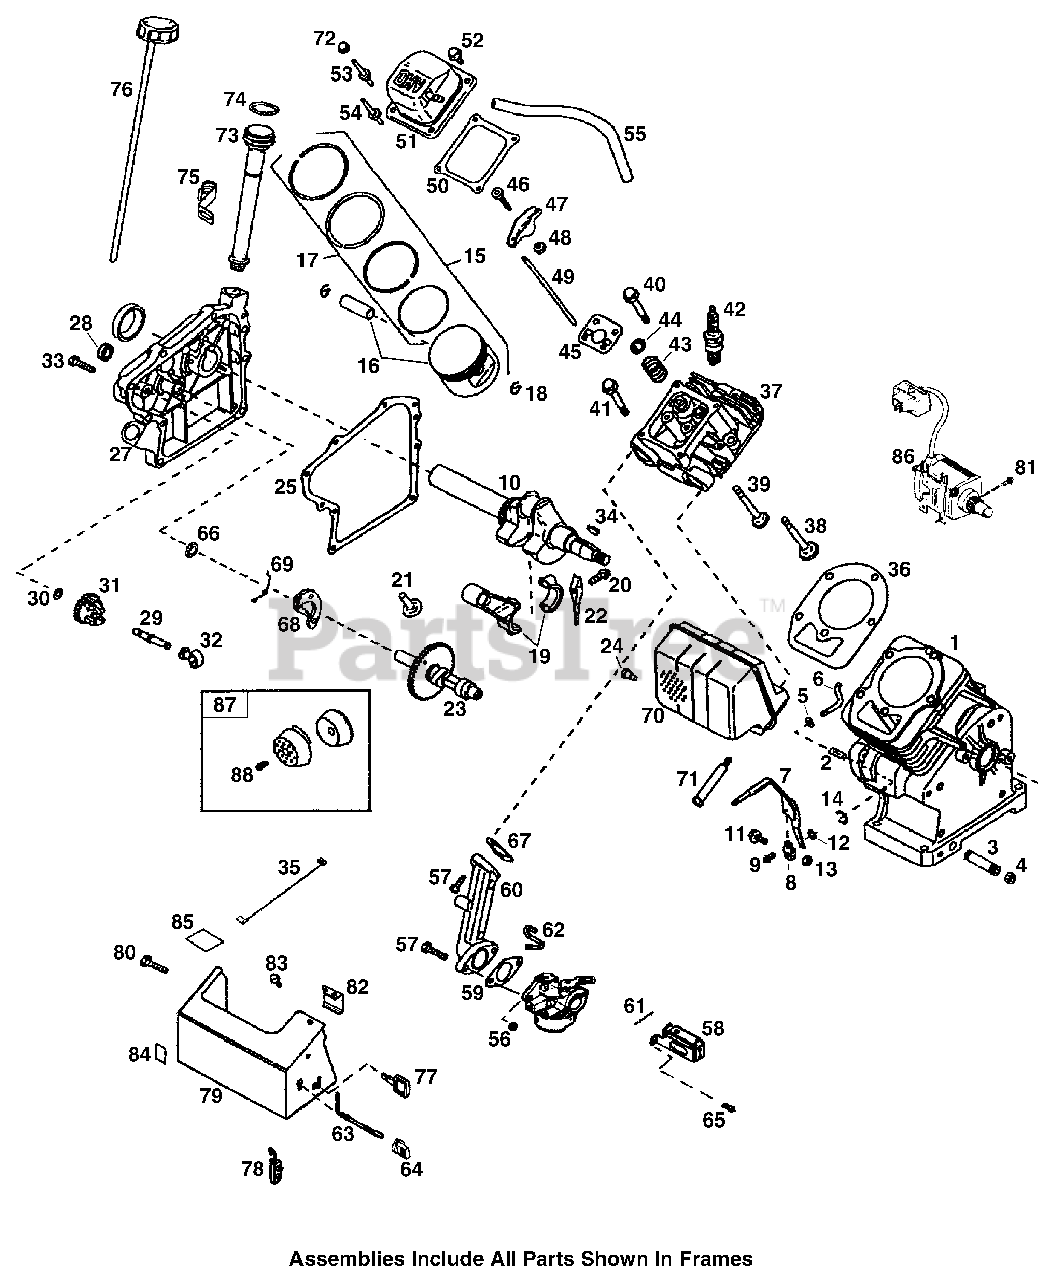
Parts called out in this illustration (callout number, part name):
1	Cylinder
2	Dowel Pin
3	Oil Drain Extension
4	Extension Cap
6	Governor Rod
7	Governor Lever
8	Governor Lever Clamp
9	Screw, Torx T-15, 8-32 x 3/8".
10	Crankshaft
11	Screw, 10-32 x 3/4".
12	Lock Washer
13	Lock Nut, 10-32
14	Retaining Ring
15	Piston, Pin & Ring Set (Standard)
16	Piston & Pin Ass’y (Standard)
17	Ring Set (Standard)
18	Piston Pin Retaining Ring
19	Connecting Rod Ass’y
20	Connecting Rod Bolt
21	Valve Lifter
22	Oil Dipper
24	Screw, 1/4-20 x 27/32".
25	Cylinder Cover Gasket
28	Camshaft Seal
29	Governor Shaft
31	Governor Gear Ass’y
32	Governor Spool
33	Screw, 1/4-20 x 1-1/4".
34	Flywheel Key
35	Ground Wire
36	Cylinder Head Gasket
37	Cylinder Head
38	Exhaust Valve (Standard)
39	Intake Valve (Standard)
40	Screw, 5/16-18 x 1-1/2".
41	Screw, 5/16-18 x 2-41/64".
42	Resistor Spark Plug (N4C)
43	Valve Spring
44	Valve Spring Cap
45	Push Rod Guide
46	Rocker Arm Stud
47	Rocker Arm
48	Nut, 1/4-28
50	Rocker Arm Cover Gasket
51	Rocker Arm Cover
52	Screw, 1/4-20 x 31/64".
55	Breather Tube
56	Nut, 1/4-20
57	Screw, 1/4-20 x 1".
58	Choke Bracket
59	Carb. to Intake Pipe Gasket
60	Intake Pipe
61	Choke Spring
62	Throttle Link
63	Choke Rod
64	Choke Knob
65	Screw, 10-32 x 1/2".
67	Intake Pipe Gasket
68	Compression Release Weight
69	Compression Release Spring
70	Muffler
71	Screw, 1/4-20 x 2-9/32".
72	Nut & Lock Washer
73	Oil Fill Tube
75	Fill Tube Clip
77	Ignition Key
79	Carburetor Cover
80	Screw, 10-32 x 1/2".
81	Screw, 1/4-20 x 5/8".
82	Carburetor Cover Bracket
83	Screw, 10-32 x 1/2".
84	Primer Decal
85	Warning Decal
86	Electric Starter Motor (110 Volt)
87	Spark Arrestor Kit
88	Screw, 8-32 x 3/8".
